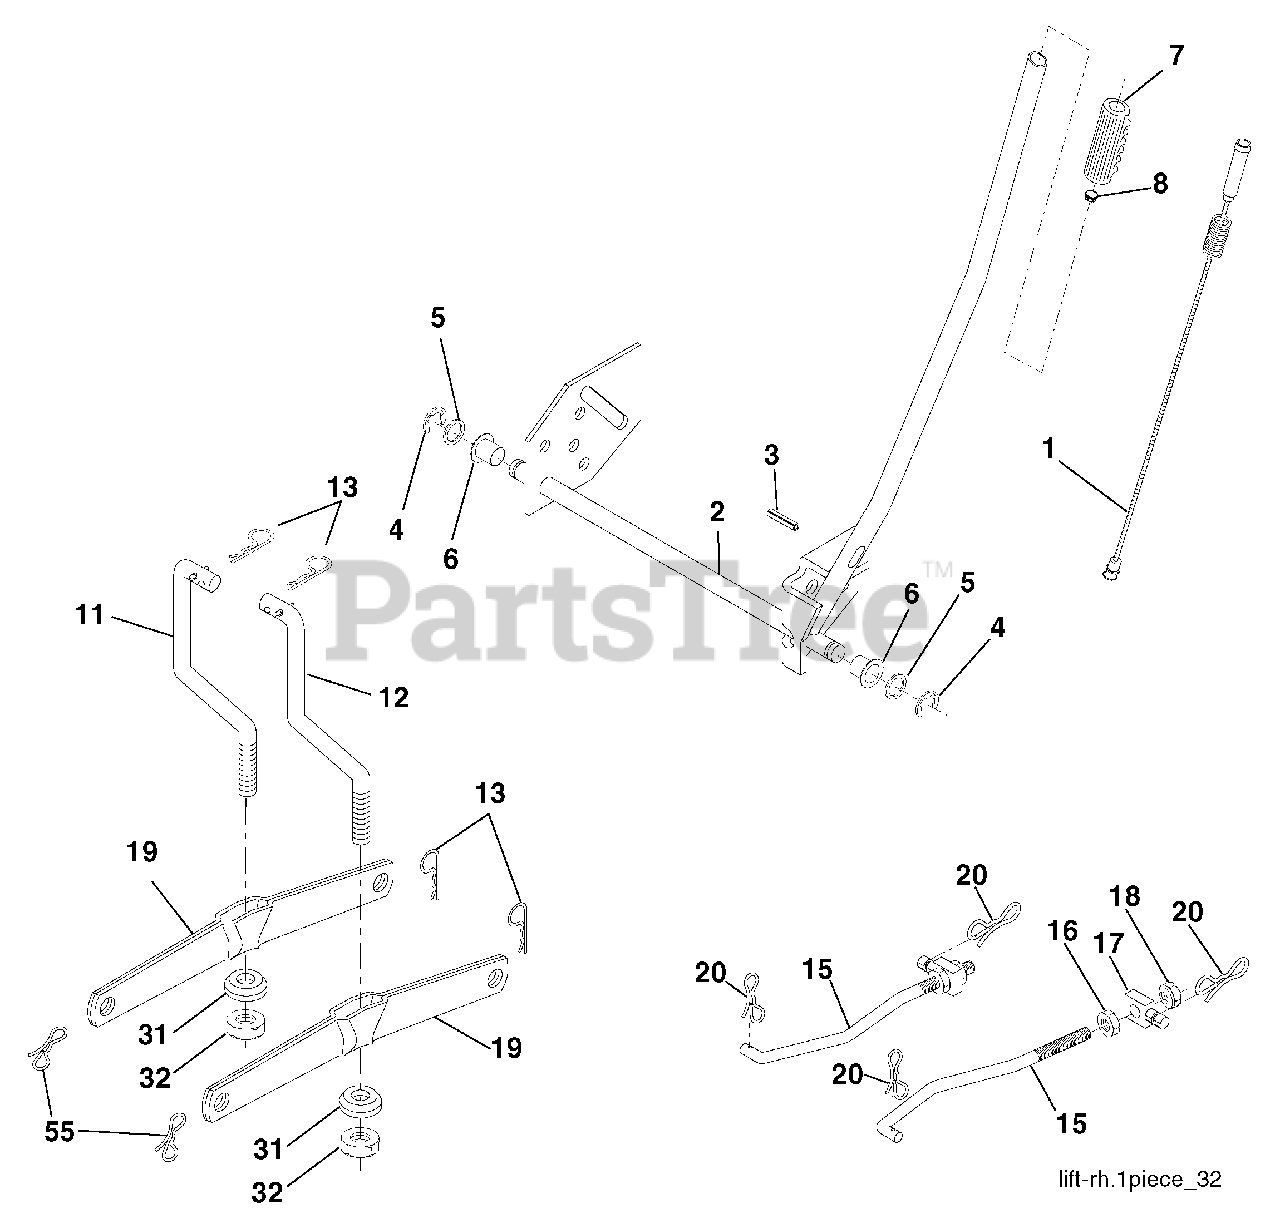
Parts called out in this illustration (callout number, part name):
1	Plunger Asm Lift Lever
2	Shaft Asm Lift RH
3	Pin Groove 1 500 Zinc
4	E Ring #5133-62
5	Washer 21/32 x 1 x 21 Ga.
6	Bearing Nylon Blk 629 Id
7	Grip Handle
8	Button Plunger Black
11	Link Lift LH Fixed Length
12	Link Lift RH Fixed Length
13	Retainer Spring
15	Link Front
16	Nut Jam Hex 1/2-13 unc
17	Trunnion
18	Nut Lockw/Wsh 1/2-13 unc
19	Arm Suspension Rear
20	Pin Cotter 7/16 Bow Tie Lock
31	Bearing Pvt Lift
32	Nut Crownlock 3/8-24
55	Pin Cotter 5/16 Bow Tie Lock
